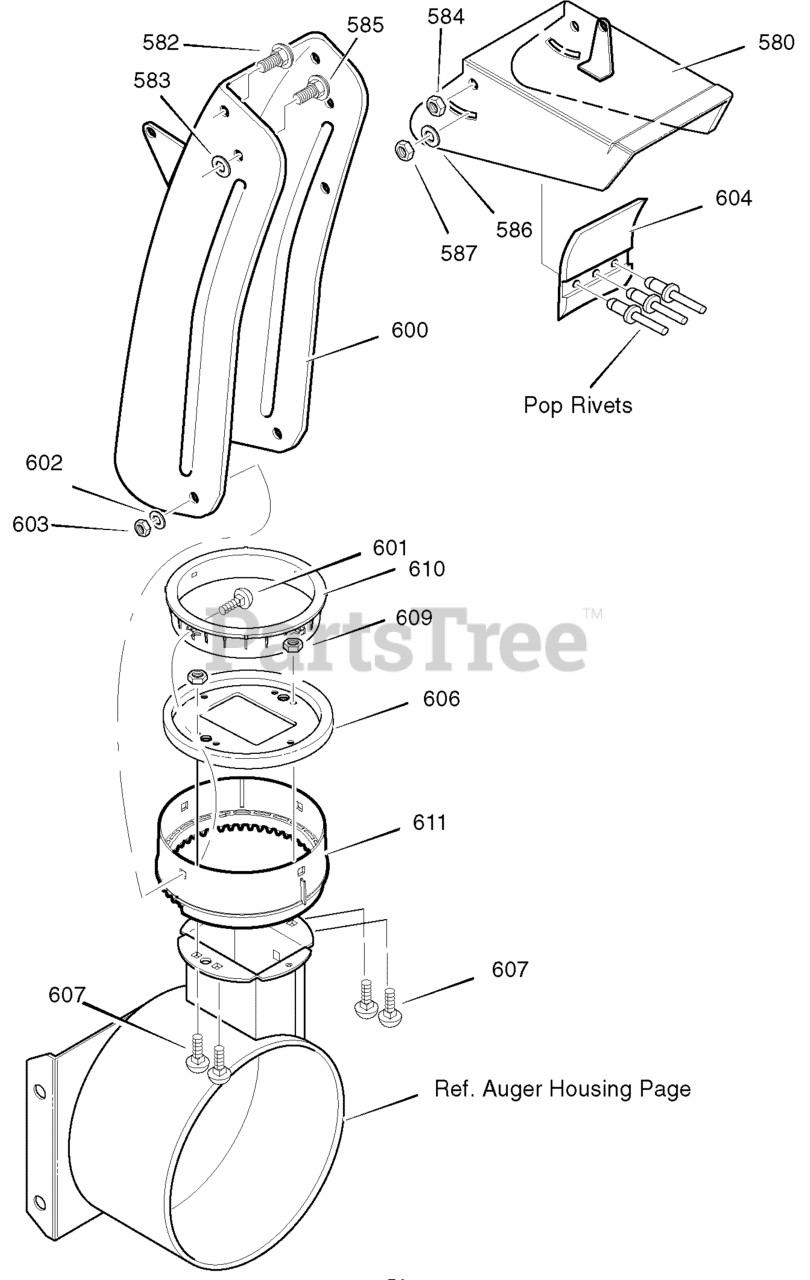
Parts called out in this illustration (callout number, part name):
580	CHUTE, UPPER W/REMOTE
582	SCREW, 5/16-18 x 0.75
584	NUT
585	SCREW, 5/16-18 x 0.75
586	PLASTIC WASHER
587	NUT
600	CHUTE, LOWER W/REMOTE
601	BOLT
602	WASHER, FLAT
603	NUT
606	CHUTE COLLAR
610	RETAINER, RING INNER
611	RETAINER, RING OUTER
